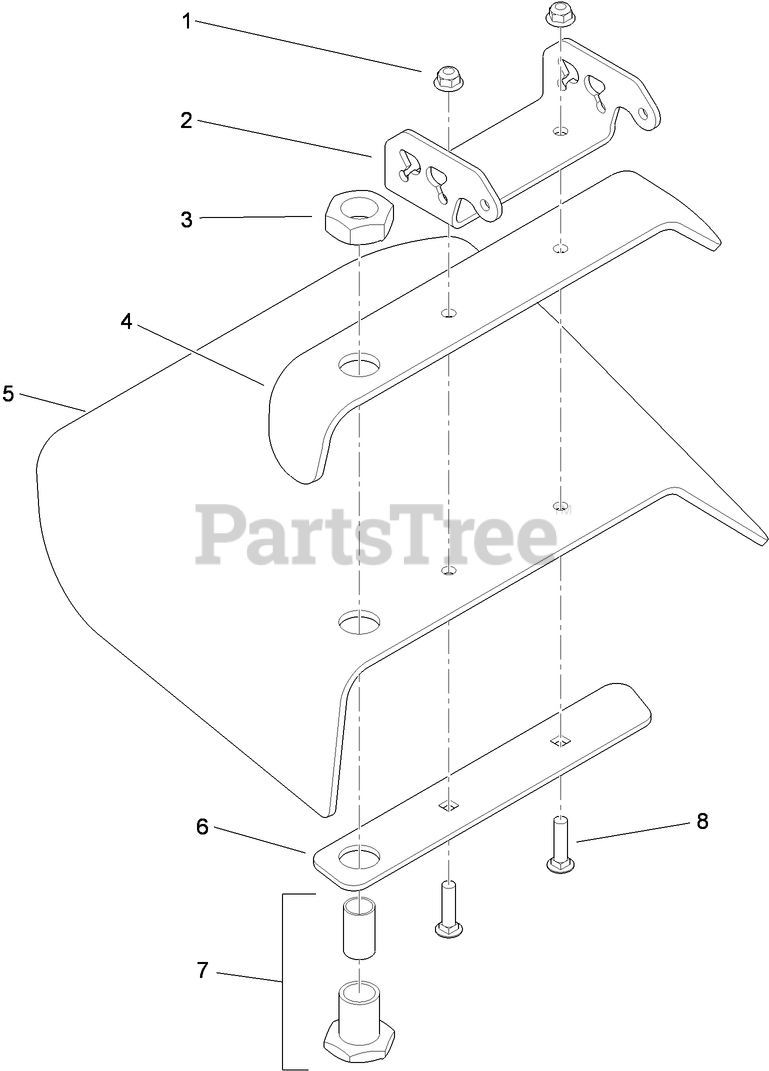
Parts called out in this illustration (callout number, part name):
1	NUT-HF, NI
2	BRACKET-DEFLECTOR
3	NUT-JAM
4	BRACKET-DEFLECTOR
5	DEFLECTOR-RUBBER
6	STRAP-DEFLECTOR
7	HUB ASM
8	SCREW-CARR
